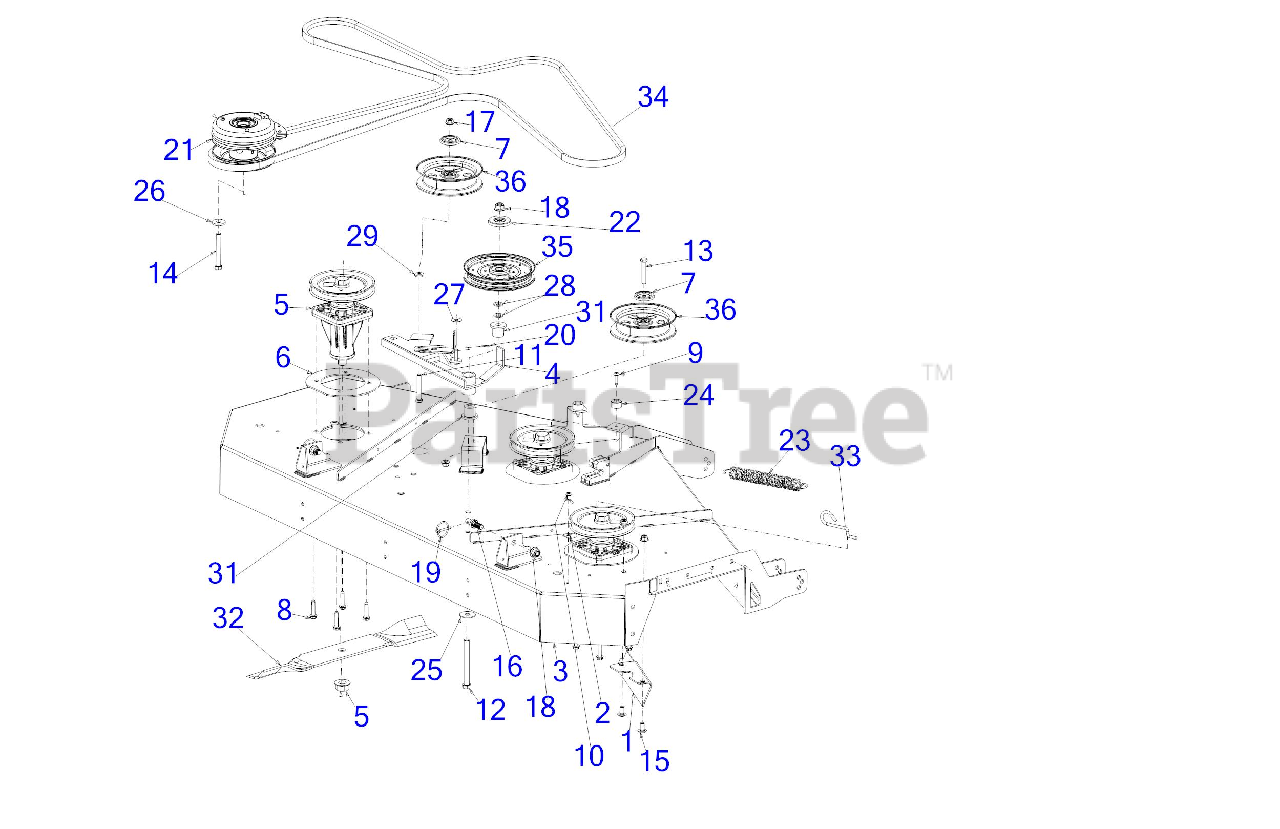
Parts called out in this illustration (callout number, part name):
2	HOOK RETAINER BRACKET
3	60" FAB DECK SHELL
5	SPINDLE ASSEMBLY
7	PULLEY CAP 1.875 DIA
8	SCREW 5/16-18 x 1.50
9	SCREW 1/4-20 x 1.0
10	SCREW 1/4-20 X.500
11	HEX SCREW-3/8-16X2.5 GR5
12	SCREW 1/2-13 x 4.5 GR 5
13	SCREW 3/8-16 x 2.25 GR5
14	SCREW 7/16-20 x 3.25 GR5
15	CARRIAGE BOLT 3/8-16 x .75
20	COTTER PIN 3/32
21	ELECTRIC PTO CLUTCH
22	PULLEY CAP 1/2"
23	EXTENSION SPRING
25	WASHER .51 x 1.5 x .07
26	FLAT WASHER .445 x 1.248 x .170
27	FLAT WASHER
28	FLAT WASHER
29	FLAT WASHER
31	SHOULDER SPACER
32	21" BLADE (HI LIFT)
32	Cub Cadet 60" BLADE SET
32	Genuine Factory Parts 60" BLADE SET
32	LOW-LIFT 21"BLADE (60"DECK)
32	BLADE-HI LIFT 21.0
32	BLADE-21"MULCH 60"
32	21" XTREME BLADE
33	DECK SPRING HOOK
34	DECK BELT B x 161.75
34	Cub Cadet DECK BELT (B x 161.75)
35	IDLER PULLEY 6.0" DIA
36	5" FLAT IDLER PULLEY
